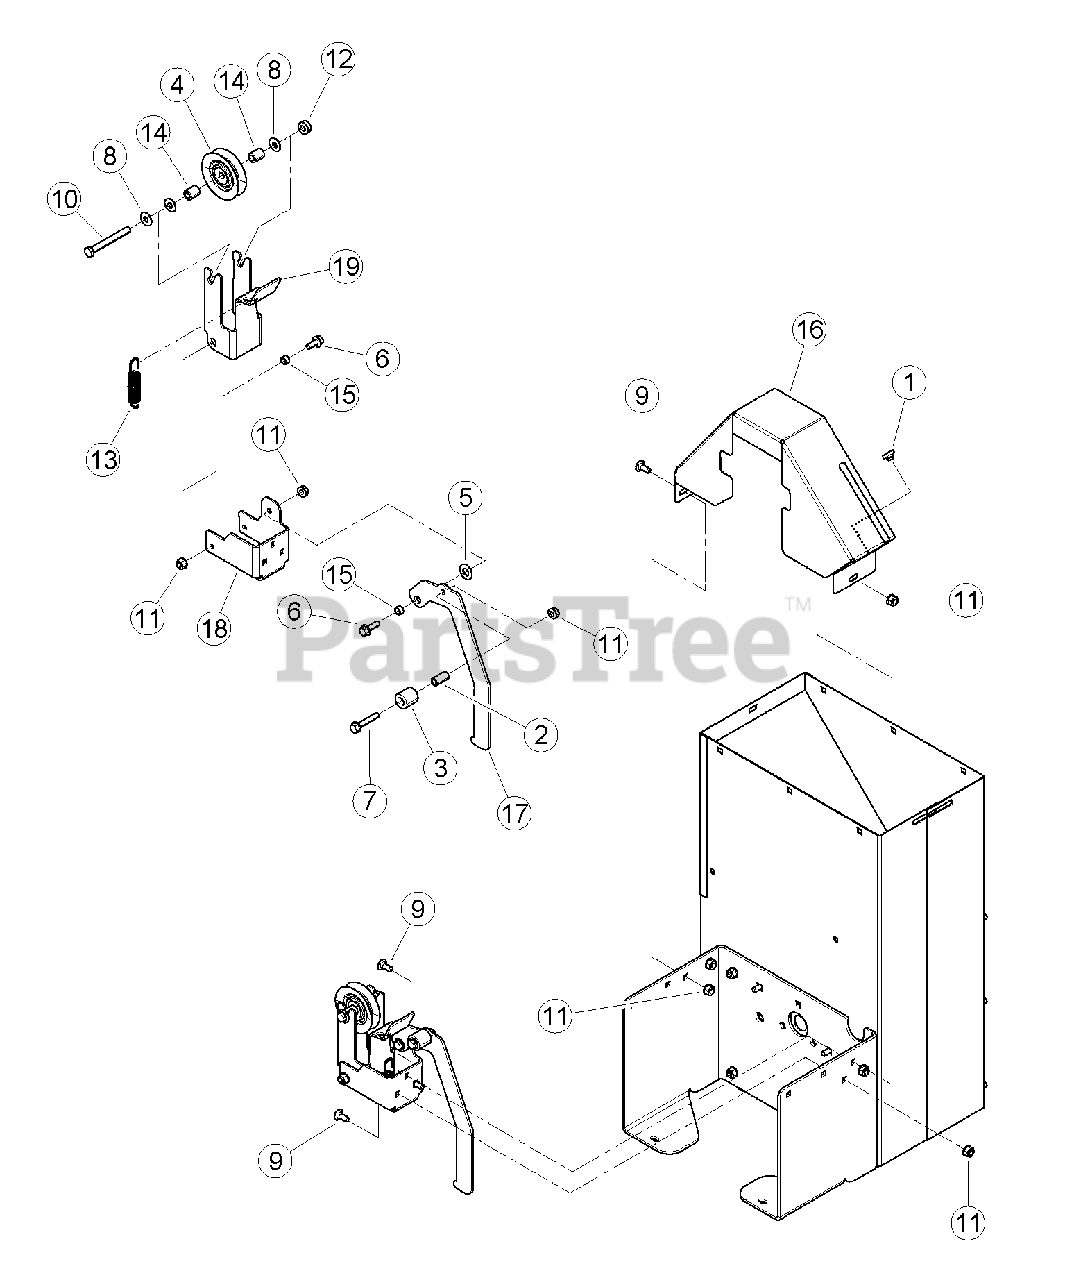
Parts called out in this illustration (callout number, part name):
1	BOLT, 5/16 X 3/4 SERRATED FLANGE NF
2	BOLT, 5/16 X 1-1/2 FLANGE NC
3	WASHER, 5/16 FLAT ZP - SC3305E ONLY
4	BOLT, 5/16 X 1 GR5 CRG ZP - SC3305E ONLY
5	NUT, 5/16 NE NYLOCK ZP - SC3305E ONLY
6	KEY, 1/4 SQUARE X 1-1/2 LONG PLAIN
7	BOLT, 5/16 X 8-3/4 L-TYPE BATTERY - SC3305E ONLY
8	NUT, 5/16-18 NYLOCK-FLANGE
9	BELT, 29" C/S
10	CABLE, 33" POS - R/R WITH BOOT - SC3305E ONLY
11	CABLE, 9" NEG - R/R - SC3305E ONLY
12	PULLEY, CAST 4" OD 1" BORE B GRV
12	PULLEY, CAST 4" OD 3/4" BORE B GR - SC3206 ONLY
13	ENGINE, 306CC B&S HORIZONTAL ELECTRIC (FOR SERVICE SEE ENGINE OWNER'S MANUAL OR NEAREST BRIGGS & STRATTON INDUSTRIAL ENGINE DEALER)
13	ENGINE, 306CC B&S HORIZONTAL (FOR SERVICE SEE ENGINE OWNER'S MANUAL OR NEAREST BRIGGS & STRATTON INDUSTRIAL ENGINE DEALER)
13	ENGINE, 900 SERIES B&S HORIZONTAL (FOR SERVICE SEE ENGINE OWNER'S MANUAL OR NEAREST BRIGGS & STRATTON INDUSTRIAL ENGINE DEALER)
14	ANGLE, BATTERY HOLD DOWN - SC3305E ONLY
15	WELDMENT, BATTERY BOX - SC3305E ONLY
16	PLATE, ENGINE MOUNTING
17	GUIDE, BELT
